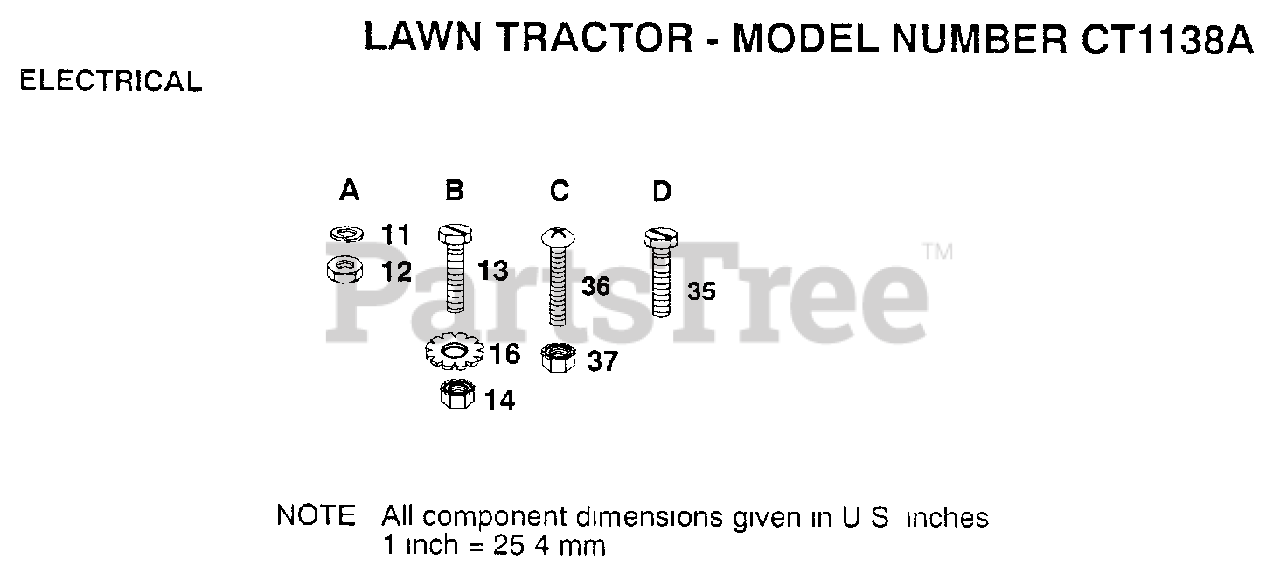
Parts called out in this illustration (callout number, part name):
12	NUT
13	BOLT
14	NUT
35	SCREW
37	"NUT,KEPS"
